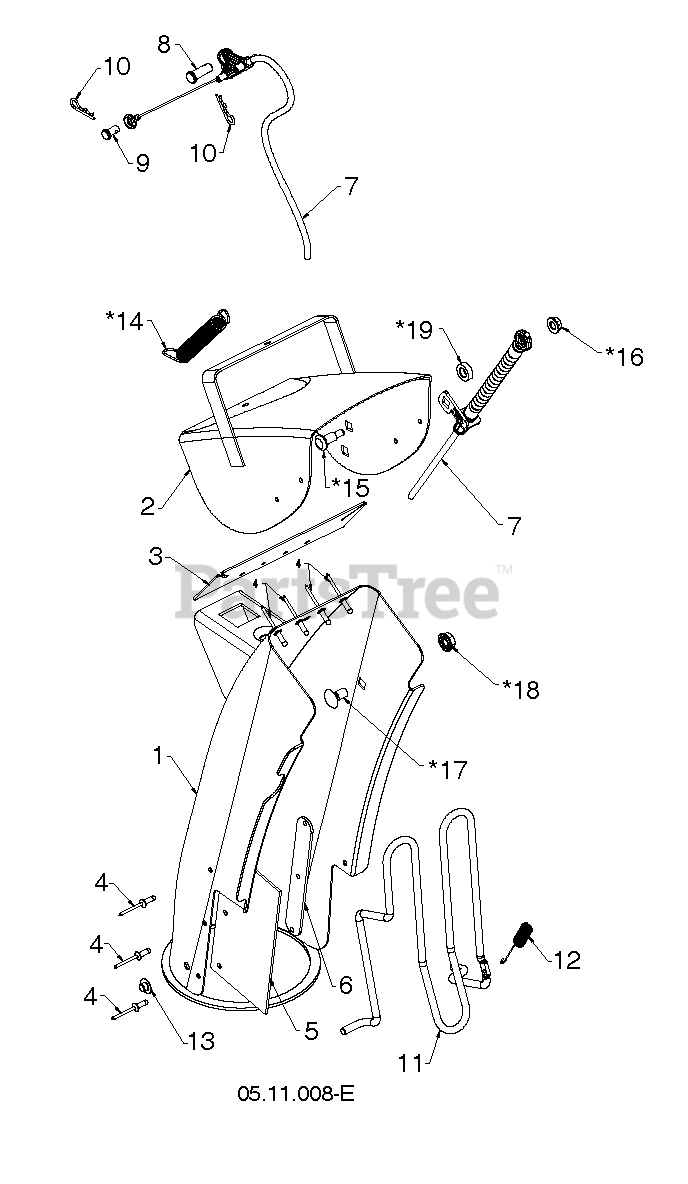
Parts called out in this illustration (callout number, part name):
1	ASM.CHUTE/DEFLECTOR.668
7	CABLE CONTROL.CHUTE.DEFL.BOWDE
8	PIN CLEVIS 5/16X.875
9	PIN CLEVIS .25 X .31
10	HAIRPIN.SOFT.ZINC.059X1.125
11	ROD.GUARD.CHUTE (2 2)
12	SPRING.CHUTE.GUARD
13	NUT
14	SPRING.DEFLECTOR.REM.CHUTE
15	BOLT.CARR.W.3125 SHLDR..25-20
16	NUT.HEX.LRG.FLANGE.1/4-20.LOCK
17	BOLT CAR BLK 5/16-18 X 5/8
18	LOCKNUT-FLANGE 5/16-18
19	WASHER.NYLON.326 X.625 X.205
